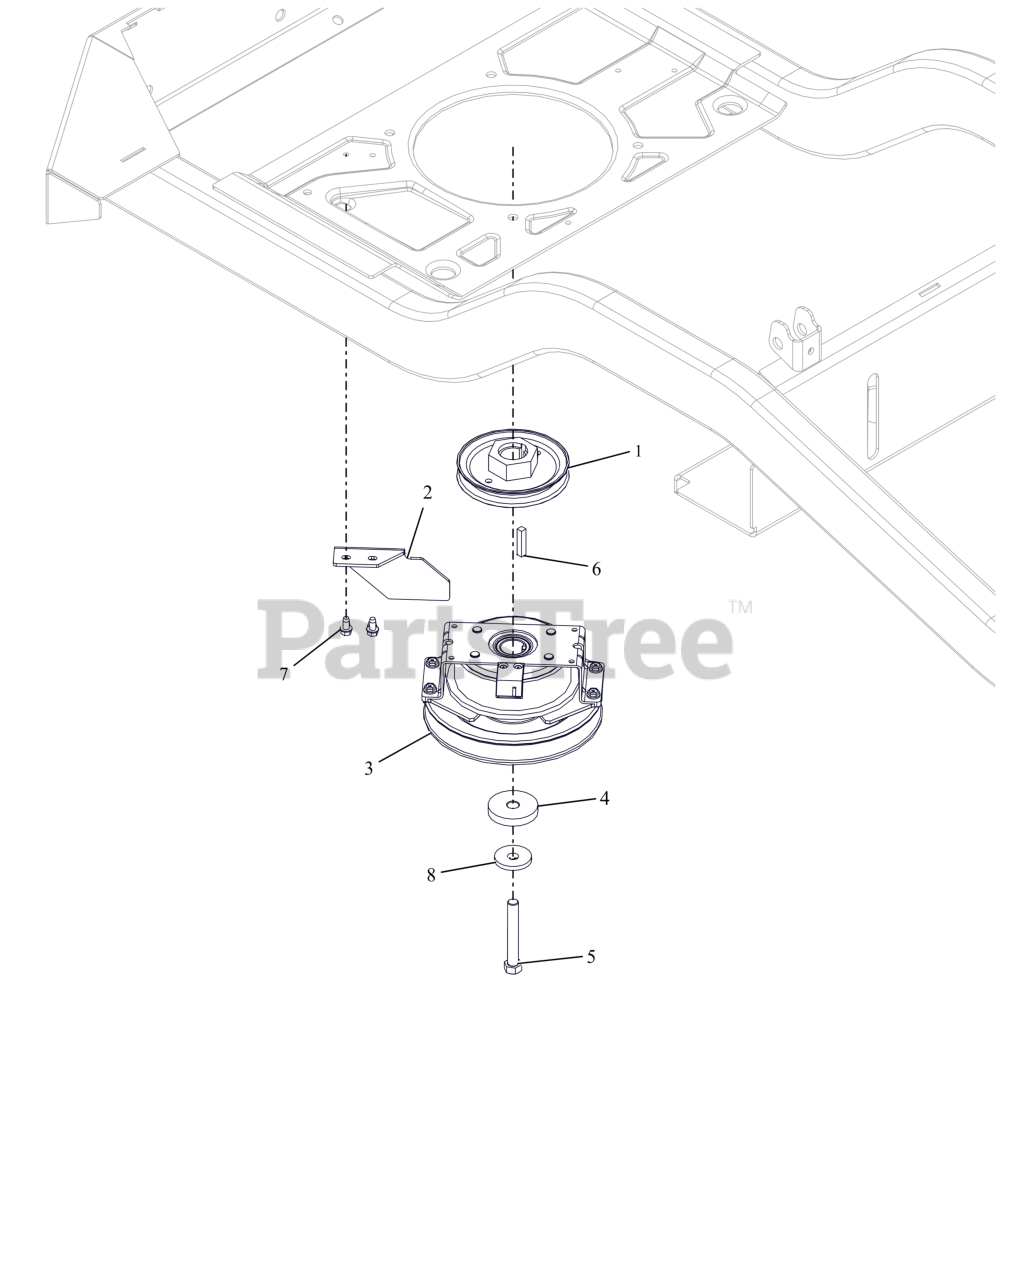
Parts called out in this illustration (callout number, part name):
1	WLDMT,PULLEY-4.50ODX1.003
2	BRKT, CLUTCH STOP HD
3	CLUTCH, OGURA DBL SPRG
4	SPACER, .474/.459X2.00X.350
5	BLT, HEX .44-20X3.00 G8 ZCC NT
6	KEY-SQ .25 X 1.25 X .25 SAE
7	SCR-TAP .25-20X.50 HWH ZCC
8	WASHER, 7/16" SPRING DISK
